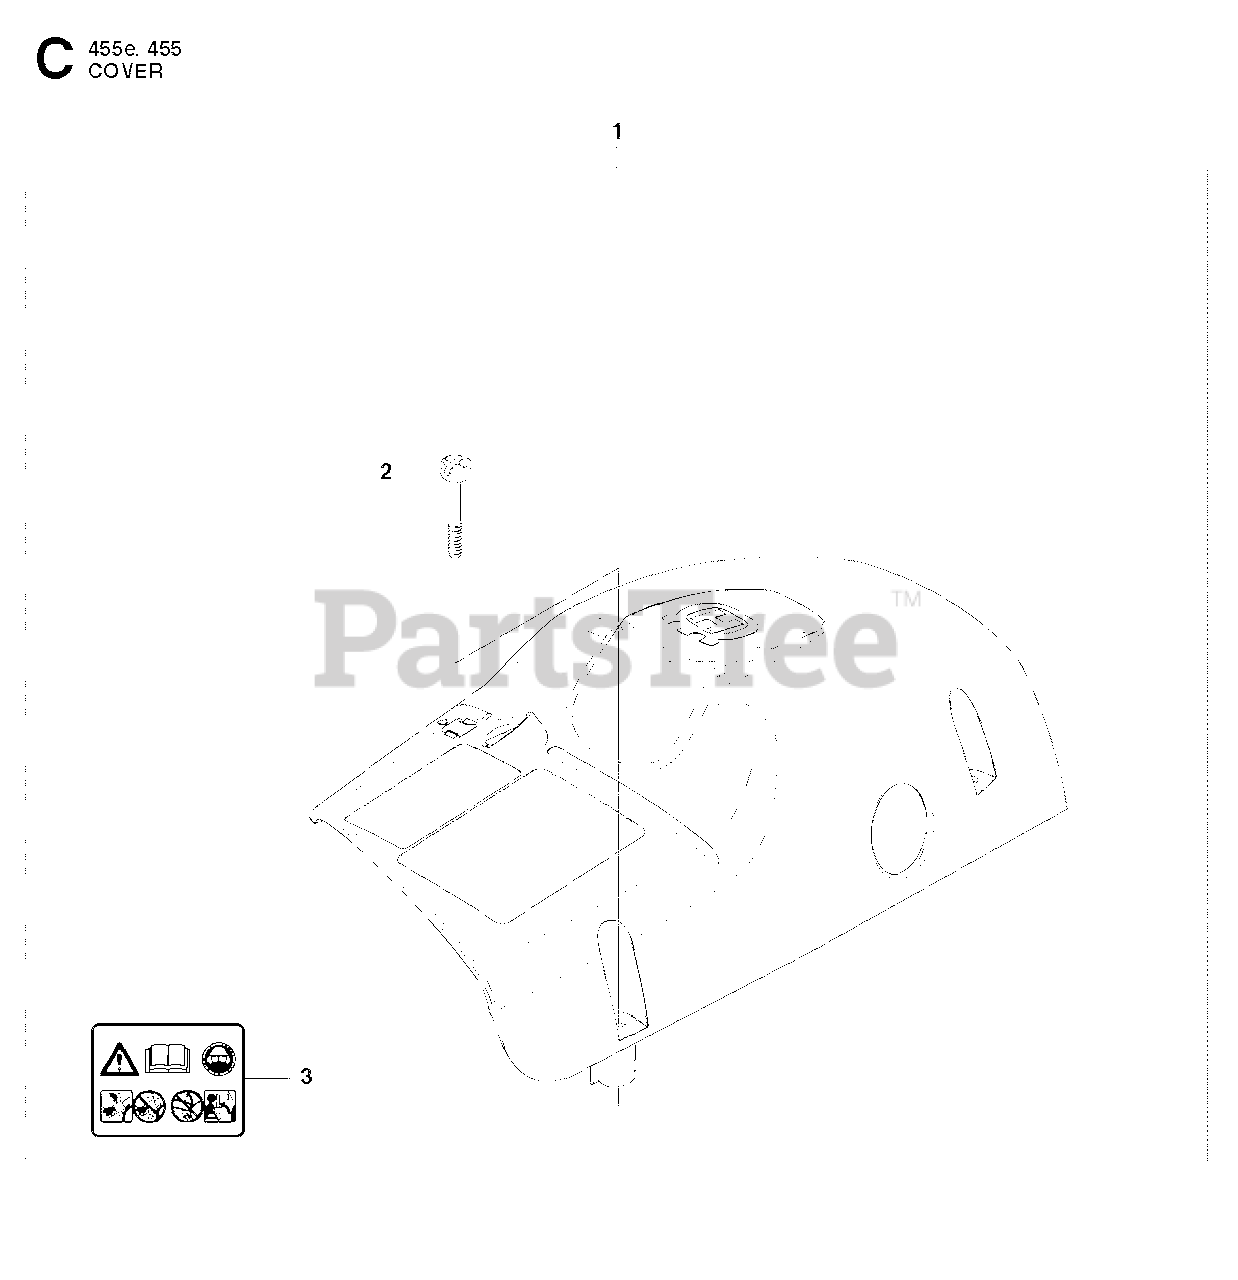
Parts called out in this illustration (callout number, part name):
1	CYLINDER COVER
2	SCREW
3	DECAL
